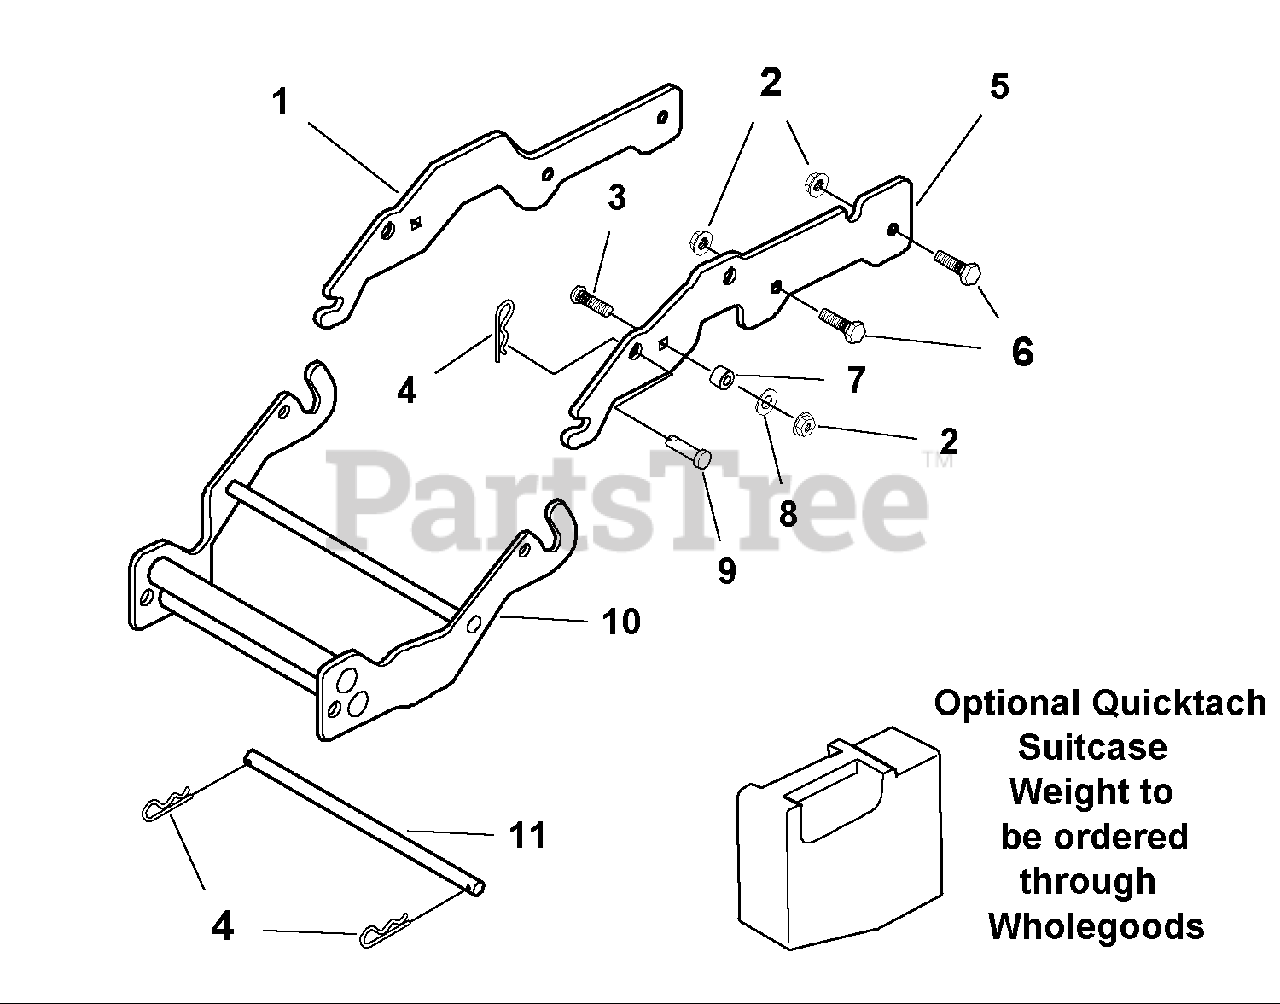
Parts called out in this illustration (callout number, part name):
1	PLATE, Mounting RH
2	NUT, Hex Flange Whizlock, 3/8-16
3	BOLT, Carriage, Short Neck, 3/8-16 x 1-1/2
4	CLIP, Hair Pin
5	PLATE, Mounting LH
6	CAPSCREW, Hex Head, 3/8-16 x 1
8	WASHER
9	PIN, Yoke, Drilled
10	HITCH ASSEMBLY
